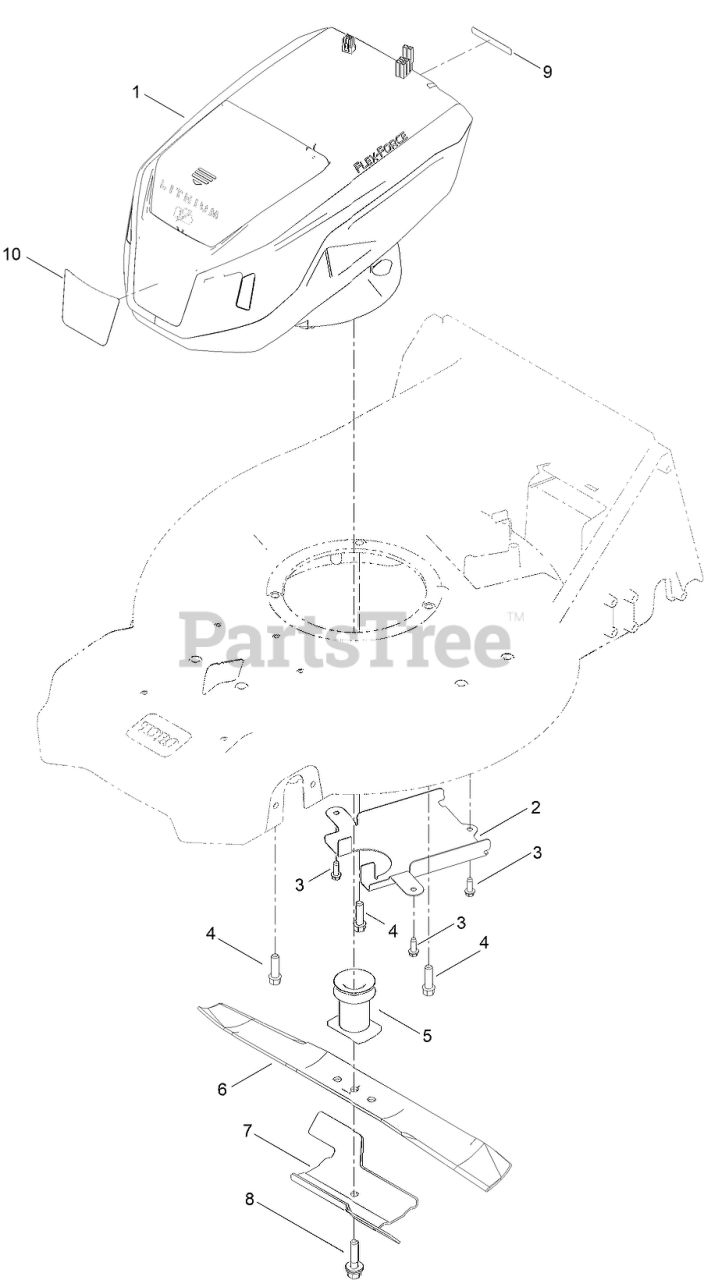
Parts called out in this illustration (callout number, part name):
1	MOTOR MODULE 60V
2	COVER-BELT, BOTTOM
3	SCREW-HWHTF
4	SCREW-TAPTITE
5	DRIVER-BLADE
6	BLADE-21IN, RECYCLING
6	BLADE-21IN RECYCLING
7	ACCELERATOR-BLADE
8	BOLT-BLADE
9	DECAL-WARNING
10	DECAL-60V
